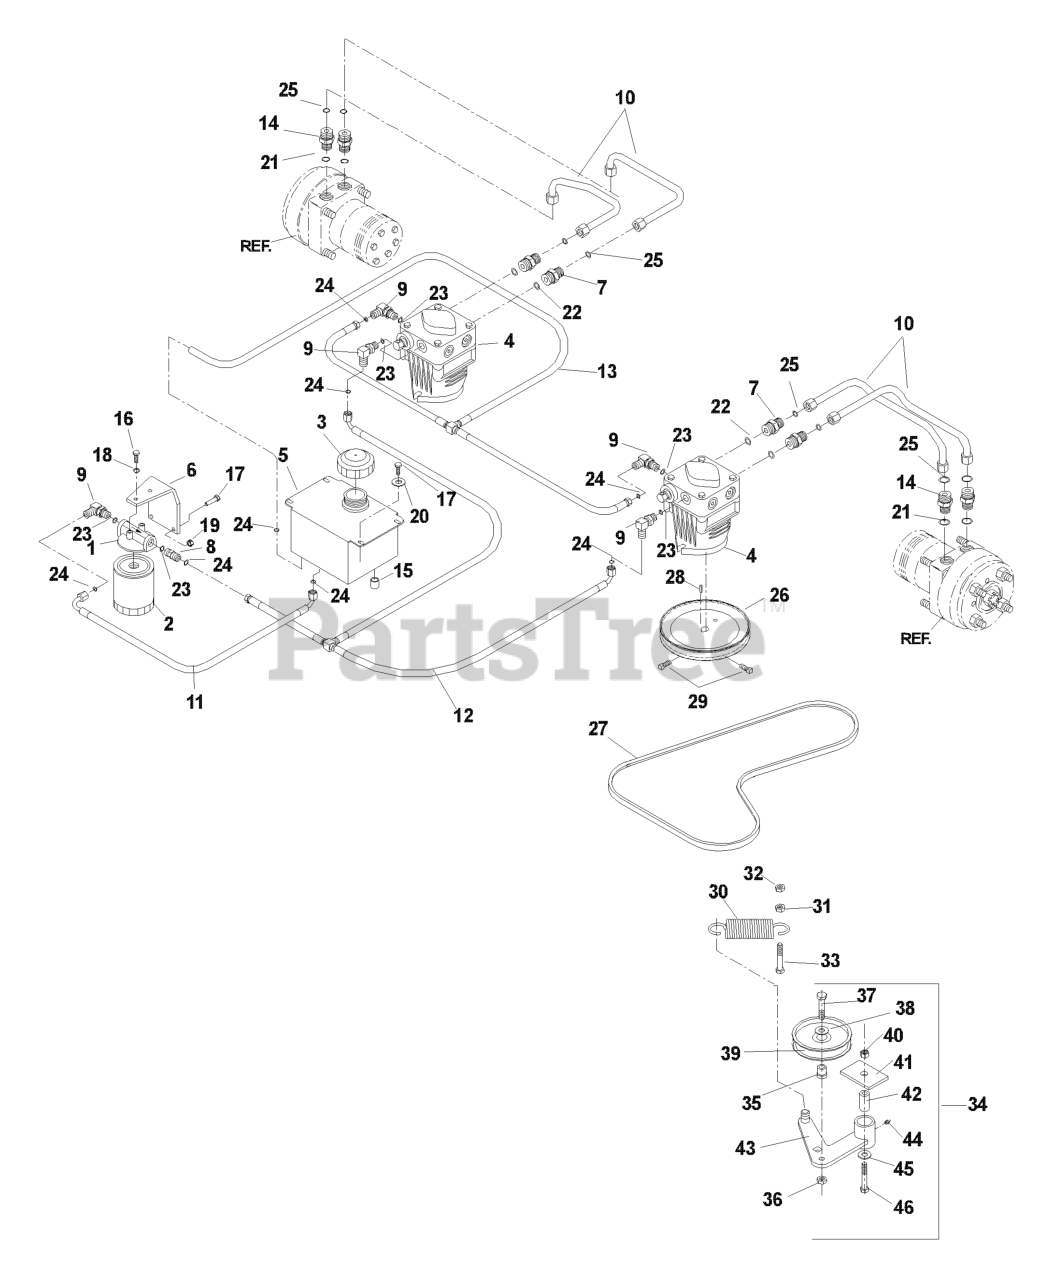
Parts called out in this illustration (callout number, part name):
1	FILTER HEAD
2	HYDRAULIC OIL FILTER
3	HYDRAULIC CAP
4	PUMP
6	OIL FILTER BRKT
7	FITTING, STRAIGHT F6400-8-8-0
8	STRAIGHT FITG
9	ELBOW, F6801-6-6-0 90 DEGREE
10	HYDRAULIC HOSE
12	TEE ASSEMBLY
13	TEE ASSEMBLY
15	NUT 9/16-18 JIC CAP
16	HCS 1/4C X 5/8
17	HCS 1/4C X 3/4 HCS
18	LOCKWASHER 1/4"
19	NUT.1/4-20.HEX.NYLOC.ZD
20	WASHER 1/4 FLAT
27	PUMP BELT
28	KEY 5 MM SQ X 25 MM
29	SCREW 5/16C X 5/8 SQ HEAD
31	NUT 3/8C WHIZ
32	NUT 3/8-16 NYLOC
33	HCS 3/8C X 2
34	IDLER ARM ASM
35	BUSHING, IDLER FLANGE
36	NUT 3/8C CENTERBLOCK
37	HCS 3/8-16 X 1 3/4 GR5
38	WASHER 3/8 FLAT
39	IDLER PULLEY
40	NUT 1/2-13 HEX NYLOC ZD
42	PIVOT BUSHING
43	IDLER ARM WLDT
44	ZERK
45	WASHER 1/2 FLAT
46	HCS 1/2C X 3 1/4
